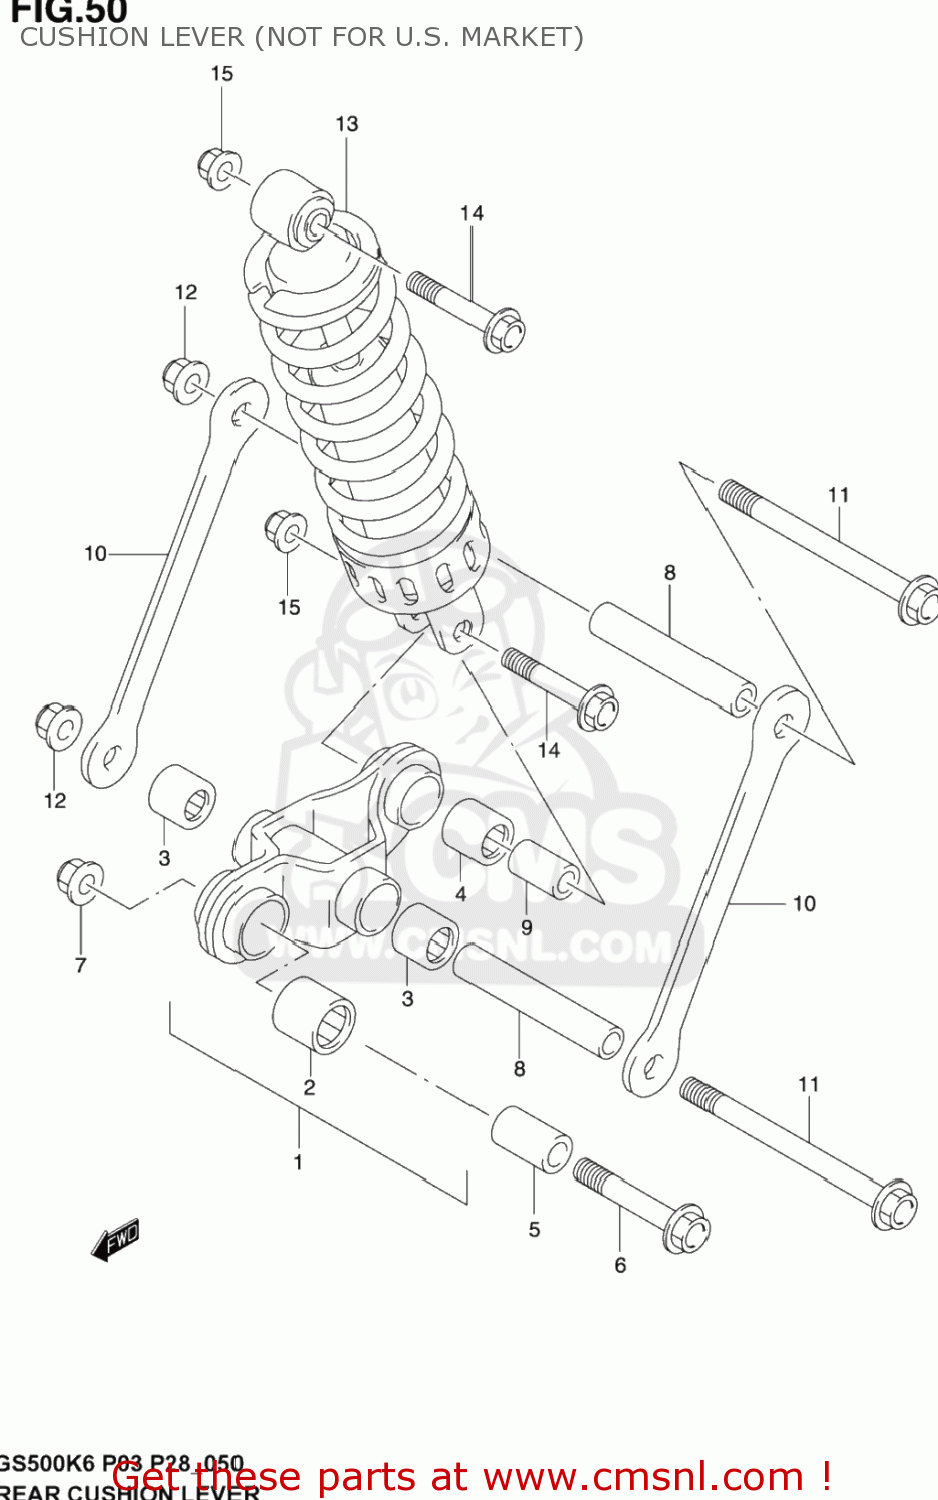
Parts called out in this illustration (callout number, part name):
1	LEVER SET,RR CUSHION
2	BEARING(20X27X26)
3	BEARING(17X24X25)
4	BEARING(17X24X26)
5	SPACER, FRONT (12X20X30)
6	BOLT(12X57)
7	NUT 12MM
8	SPACER(12X17X89)
9	SPACER, REAR (10X17X30)
10	ROD, REAR CUSHION
11	12
12	NUT 12MM
13	ABSORBER ASSY,
14	BOLT(10X52)
15	NUT
